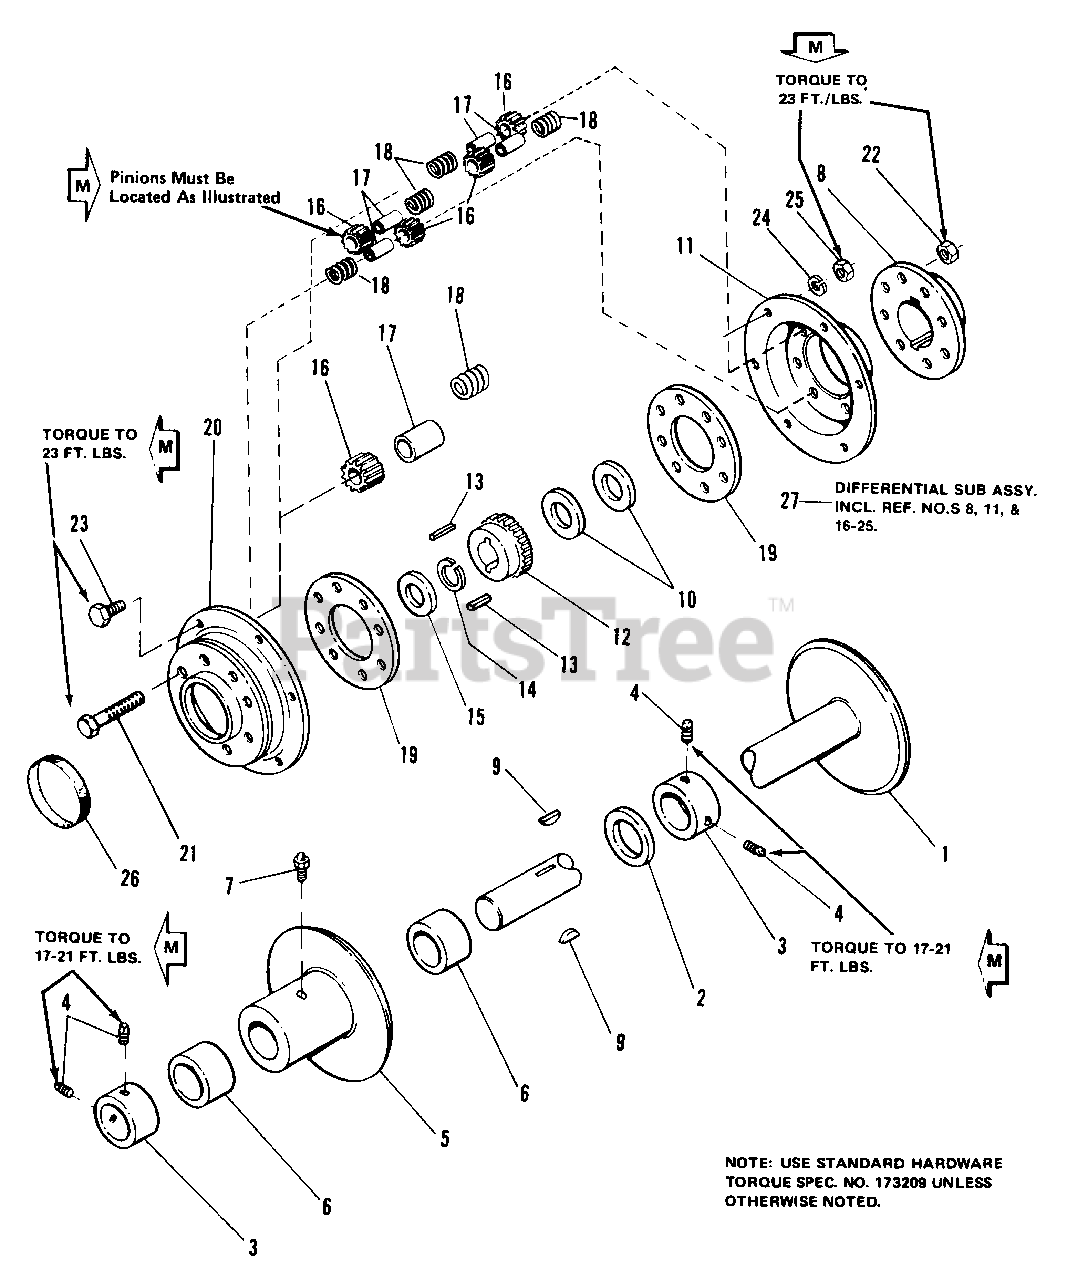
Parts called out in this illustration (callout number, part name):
1	REAR AXLE ASSEMBLY
3	COLLAR, Set
4	SETSCREW, Sq. Hd., 5/16-18 x 3/8
5	R.H. WHEEL HUB ASSEMBLY
7	FITTING, Grease
8	CARRIER, Diff.
10	WASHER, Axle
11	COVER, Diff.
12	GEAR, Diff.
13	KEY, Hi Pro, 1/4 x 3/4
14	RING, Retaining
15	WASHER, Axle
16	PINION, Diff.
17	SPINDLE, Diff. Pinion
19	RING, Spacer
20	COVER, Diff.
21	CAPSCREW, Hex Hd., 3/8-16 x 2-1/2
22	NUT, Hex, Center Lock, 3/8-16
23	CAPSCREW, Hex, 1/4-20 x 5/8
24	LOCKWASHER, 1/4
25	NUT, Hex, 1/4-14
26	SEAL, Cover
27	DIFFERENTIAL SUB ASSY (Includes Ref. No.'s 8, 11, 16-25)
